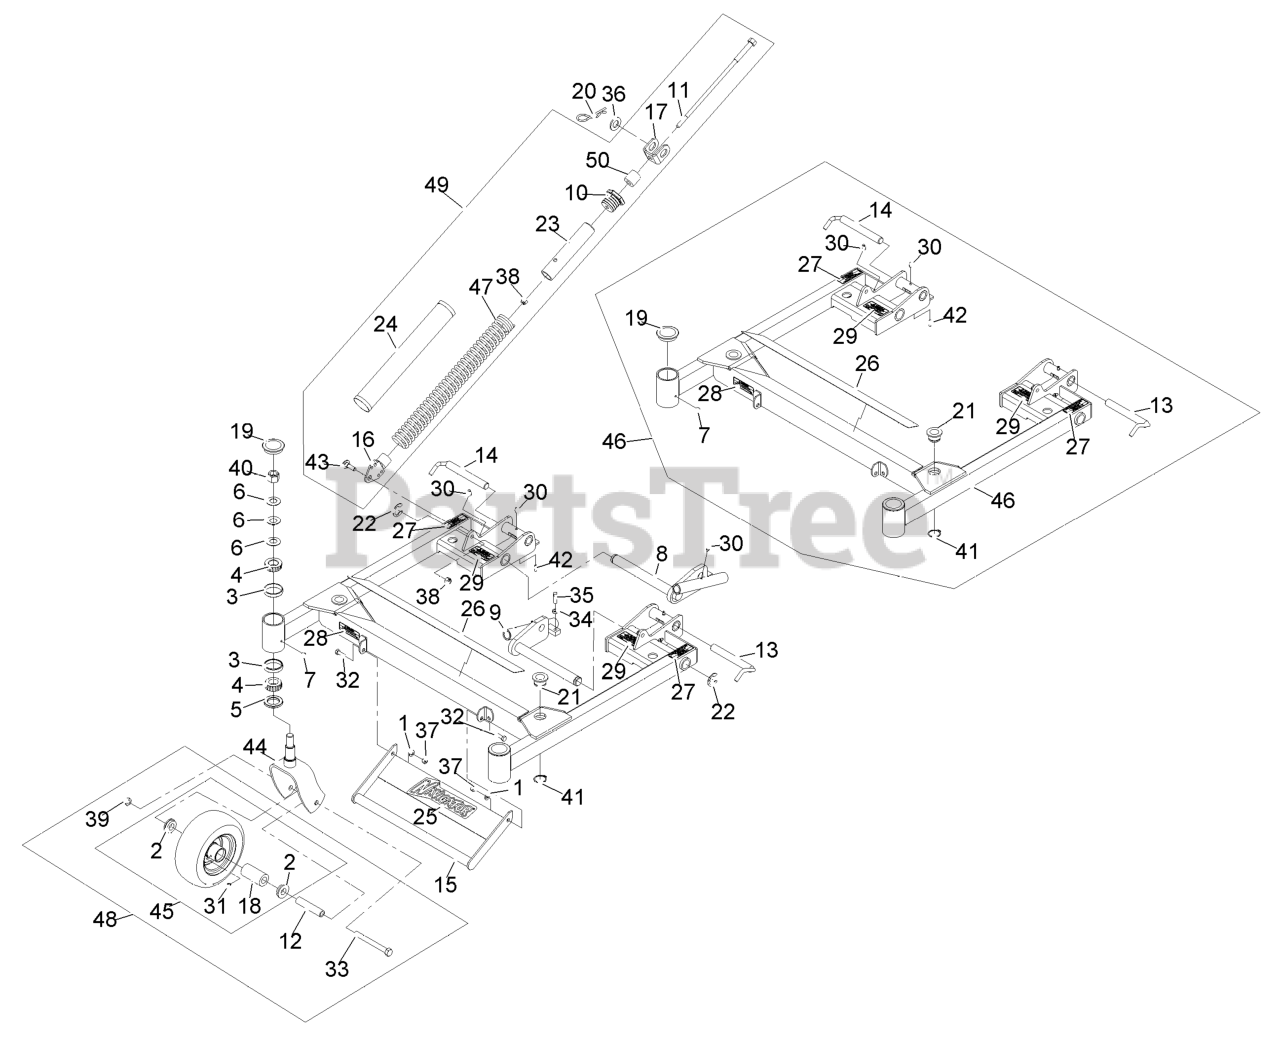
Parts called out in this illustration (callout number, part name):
1	WASHER-SPRING
2	BUSHING
3	CUP-BEARING
4	Cone-Bearing Tapered Roller
5	SEAL-GREASE
6	WASHER-BELLVILLE
8	PIVOT-DECK, RH
9	PIVOT-DECK, LH
10	PLUG-ADJUSTER, SPRING
11	SHAFT-ADJUSTMENT, SPRING
12	SPACER-CASTER, FRONT
13	LOCK-DECK, LH
14	LOCK-DECK, RH
15	ASM,DECK LIFT HANDLE W/DE
16	TENSIONER-SPRING
17	MOUNT-LIFT ASSIST, DECK
18	BEARING-ROLLER, STRAIGHT
19	CAP-GREASE
20	PIN-CUT HEIGHT
21	BUSHING-SUPPORT, DECK
22	RING-SNAP
23	SPRING-TUBE
24	COVER-SPRING, DECK
25	DECAL,NAVIGATOR MODEL
26	PAD-SKID, ANTI
27	DECAL-FOLDING DECK
28	DECAL-DANGER
29	DECAL-SPRING
30	FITTING-GREASE
31	FITTING-GREASE
32	SCREW-HH
33	SCREW-HH
34	NUT-JAM
35	SCREW-SET, SQH
36	WASHER-FLAT
37	NUT-LOCK, NI
38	NUT-LOCK, NI
39	NUT-HEX
40	NUT-LOCK, NI
41	RING-RETAINING
42	PIN-SPRING
43	SCREW-SHOULDER, HWH
44	FORK-CASTER
45	ASM,WHEEL,TIRE & BRGS 8X3
46	DECK SUPPORT ASM
47	SPRING-EXTENSION
48	ASM,FF CASTER WHEEL W/AXL
49	ASM,LIFT AST SPRING (42")
50	SPACER (PLATED)
